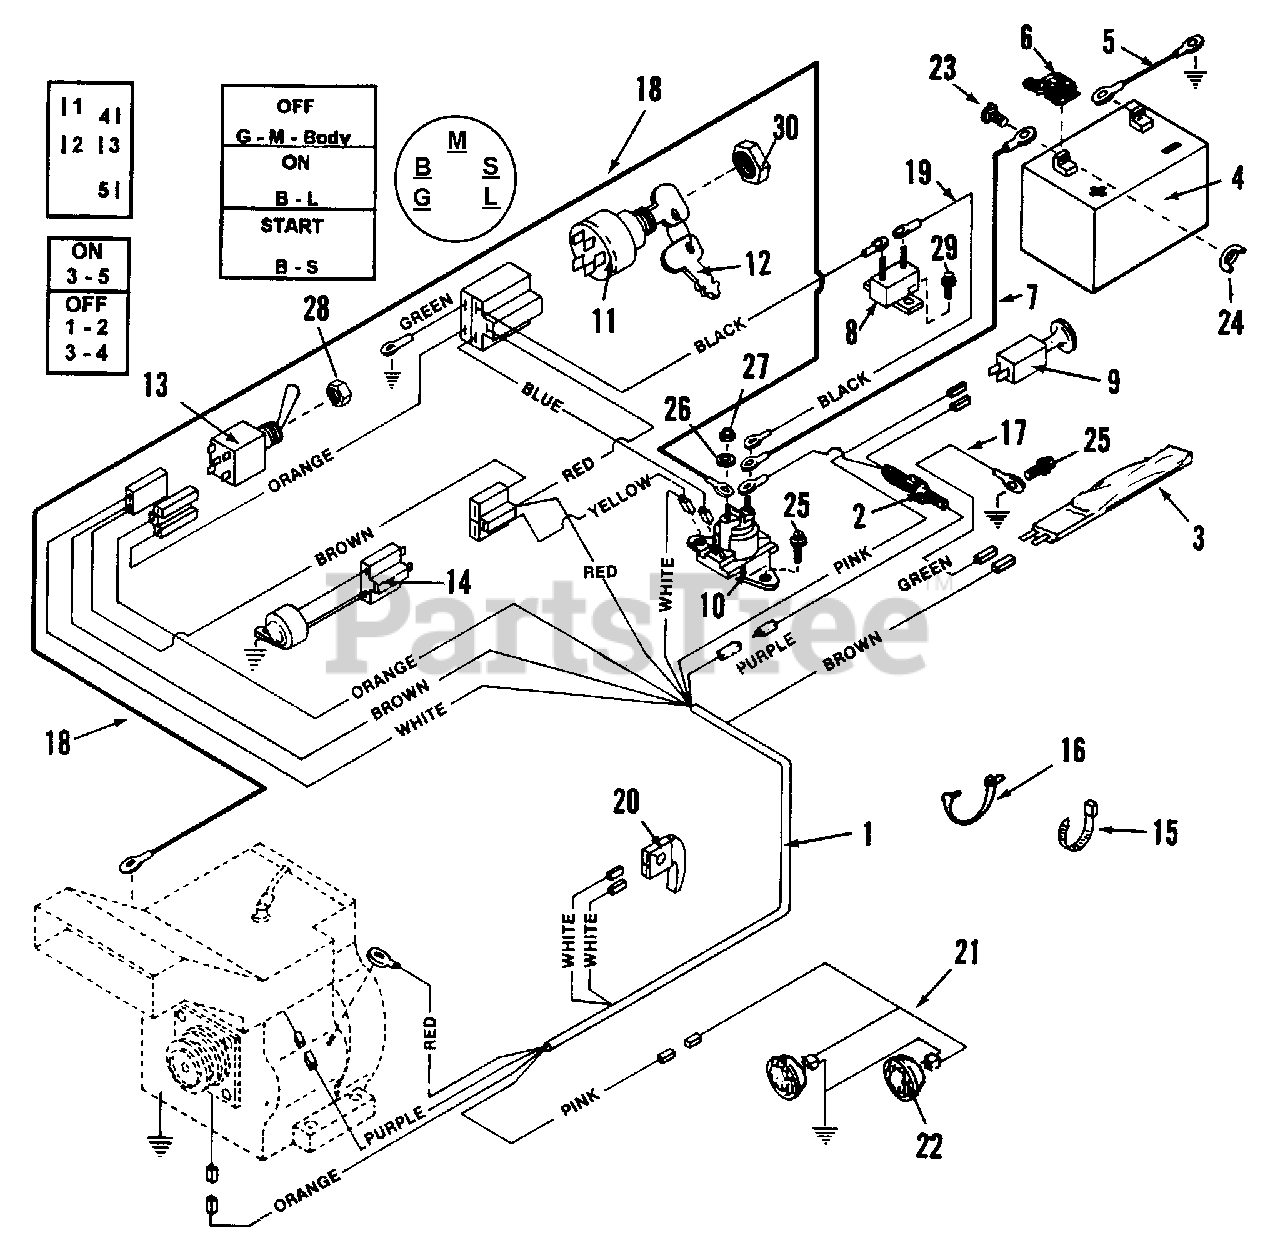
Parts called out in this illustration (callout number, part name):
1	HARNESS, Wiring
2	HARNESS, Diode
3	SWITCH, Seat Interlock
4	BATTERY 12V. 30 Amp Hour
5	CABLE, Negative (Black)
6	COVER, Positive Terminal
7	CABLE, Solenoid/Starter (11")
8	CIRCUIT-BREAKER
9	SWITCH, Headlamp
10	SOLENOID
11	KEYSWITCH
12	KEY
13	SWITCH, PTO
14	MODULE, Interlock - B&S
15	TIE, Wire
16	TIE, Cable
17	WIRE, Seat Switch to Ground
18	CABLE, Solenoid/Starter (36")
19	WIRE, Breaker to Solenoid
20	SWITCH, Clutch Interlock
21	HARNESS, Headlamp
22	HEAD-LAMP
23	BOLT, 1/4-20 X 3/4" Carriage, Grade 5
24	WING-NUT, 1/4-20
25	SCREW, 1/4-20 X 5/8" Hex Washer Self-Tap
26	WASHER, 1/4 Int. Tooth Lock
27	NUT, 1/4-20 Hex
28	NUT, Special 1/2-27 Hex
29	SCREW, #10-24 x 1/2" Hex Washer Self-Tap (Torx)
30	NUT, Special 5/8-32 Hex
